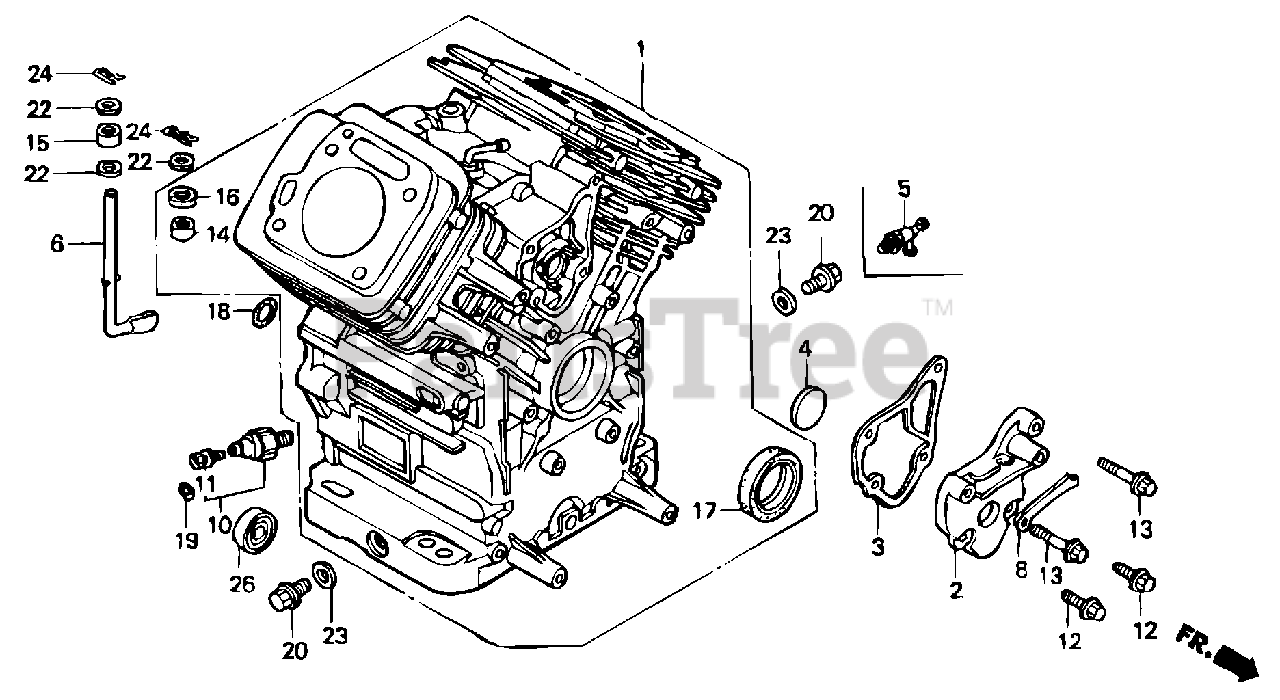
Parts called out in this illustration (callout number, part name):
1	Cylinder Assembly
2	Cover, Breather
3	Gasket, Breather Cover
4	Valve, Breather
5	Valve, Drain (14x1.5)
6	Shaft, Governor Arm
8	Clamp, Wire
10	Switch, Oil Pressure
11	Screw-washer (4x8)
12	Bolt, Flange (6x16)
13	Bolt, Flange (6x32)
14	Bearing, Needle (8x12.7x11.1)
15	Bearing, Needle (8x12x10)
16	Oil Seal (8x14x5)
17	Oil Seal (38x58x9)
18	O-ring (13x3.0)
20	Bolt, Drain Plug (14mm)
22	Washer, Plain (8mm)
23	Washer, Drain Plug (14mm)
24	Pin, Lock (8mm)
26	Bearing, Radial Ball (6003)
